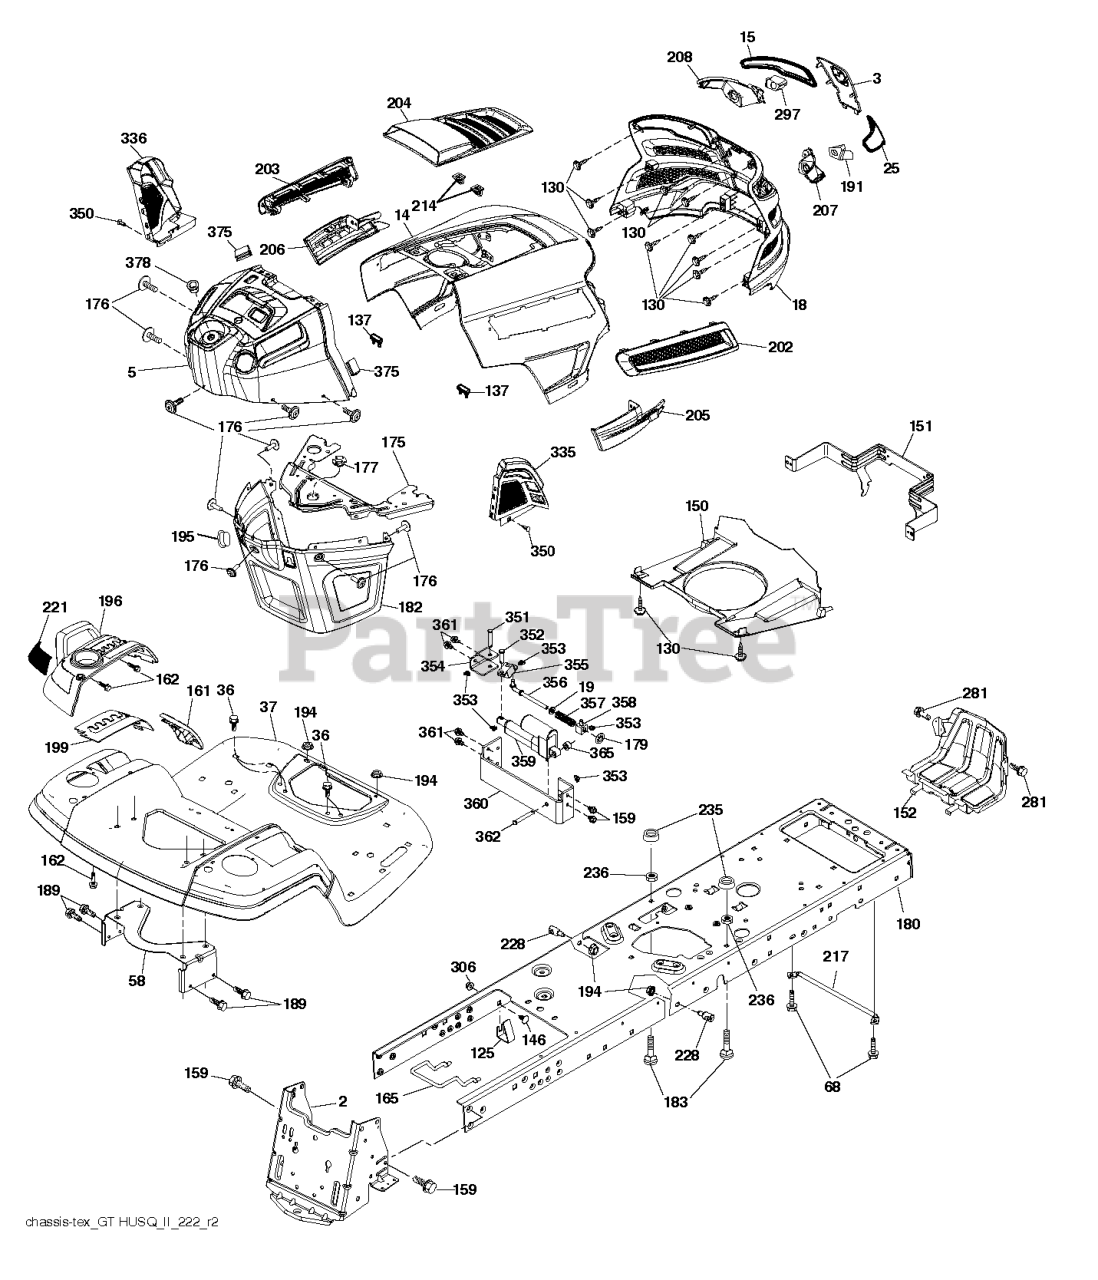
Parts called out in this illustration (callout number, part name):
2	DRAWBAR.STGT
3	APPLIQUE.SUBASM.GT.HUSQ.II
5	DASH.UPPER.ASM.GT2.S.M.PTO.SW2
14	HOOD.ASM.HUSQVARNA.GT.TEX.422
15	LENS.HEADLIGHT.LH.GTII.2011
18	GRILLE SUBASM.GT.II.LOW.HDLGHT
19	WASHER
25	LENS.HEADLIGHT.RH.GTII.2011
36	SCREW 5/16"
37	FENDER.PNT.TX.GT.CH/FW/DL.HUSQ
58	BRKT.SUPPORT.FNDR/TANK
68	SCR 5/16-18 X 1/2 SELFTAP ZN
125	CLIP.FUEL.LINE
130	SCREW.#10 X 0.750.BOS
137	BUMPER DASH
146	BOLT.RDHD.SHT.SQNK.3/8-16X5/8
150	AIR.DUCT.GTV.BLACK
151	BRACKET.PIVOT.HOOD.GT.HUSQ.II
152	SHIELD.BROWNING.PNT.GT.V2
159	SCREW, 3/8-16X3/4
161	CONSOLE.WINDOW.FUEL.HUSQ.GT
162	SCREW.HI-LO.CONSOLE
165	SUPPORT.TANK.REAR.B/TE
175	PLATE.PNT.CROSSMEMBER.HUSQ/PRE
176	SCREW.#10-24X5/8.RN.QU
177	BUSHING STEERING
180	CHASSIS LTGT BOLTED PAINTED X4
182	DASH.LOWER.COMMON.12V.ADAPTOR
183	BOLT.5/16-18X1-1/4 FULL THD
189	SCREW
191	INSERT.REFLECTIVE.RH.HUSQ.GTII
194	NUT LOCK HEX FLANGE 5/16-18
195	PLUG.HOLE.DASH.LOWER.12V.BLK
196	CONSOLE.ASM.DECKLIFT.HUSQGT.DL
199	PLATE.DECK.LIFT.HUSQVARNA.GT
202	VENT.SIDE.RH.GT.HUSQ.II.
203	VENT.SIDE.LH.GT.HUSQ.II.498
204	VENT.TOP.HUSQ.GT2
205	SIDE.TRIM.RH.GT.HUSQ.II
206	SIDE.TRIM.LH.GT.HUSQ.II.GRAY
207	HEADLIGHT.CUP.BEZEL.HUS.GT2.RH
208	HEADLIGHT.CUP.BEZEL.HUS.GT2.LH
214	CLIP.RETAINER.TINNER.
217	ROD.PIVOT.HOOD
221	REFLECTOR.LH.TEX GT HU
228	STUD.FASTNER.W/ANTI-ROTATE
235	SPACER FENDER
236	NUT.CENTERLOCK.5/16-
281	SCREW 3/8-16X1
297	INSERT.REFLECTIVE.LH.HUSQ.GTII
306	NUT LOCK FLG 3/8-16 UNC
335	COVER.LOWER.DASH.RH.BLACK
336	COVER-LH.LOWER.DASH.GT2.BLACK
350	CLIP.X-MAS.TREE
351	PIN.CLEVIS.375X2.125
352	PIN.CLEVIS.(.375 X 1.25)
353	CLIP RETAINER
354	SUPPORT.BELLCRANK
355	BELLCRANK.PIVOT.LOCK.DIFF
356	LINK.LOCK.DIFF
357	SPRING.COMPRESSION
358	GUIDE.SWIVEL
359	ACTUATOR.ELECTRIC
360	BRACKET.ACUATOR
361	SCREW LT.3/8-46X5/8
362	PIN.CLEVIS.(.375 X 2.42)
365	SPACER.NYLON.75" X .4375
375	BUMPER CLIP-ON. DASH 1"
378	BUSHING FLANGE; PLASTIC
